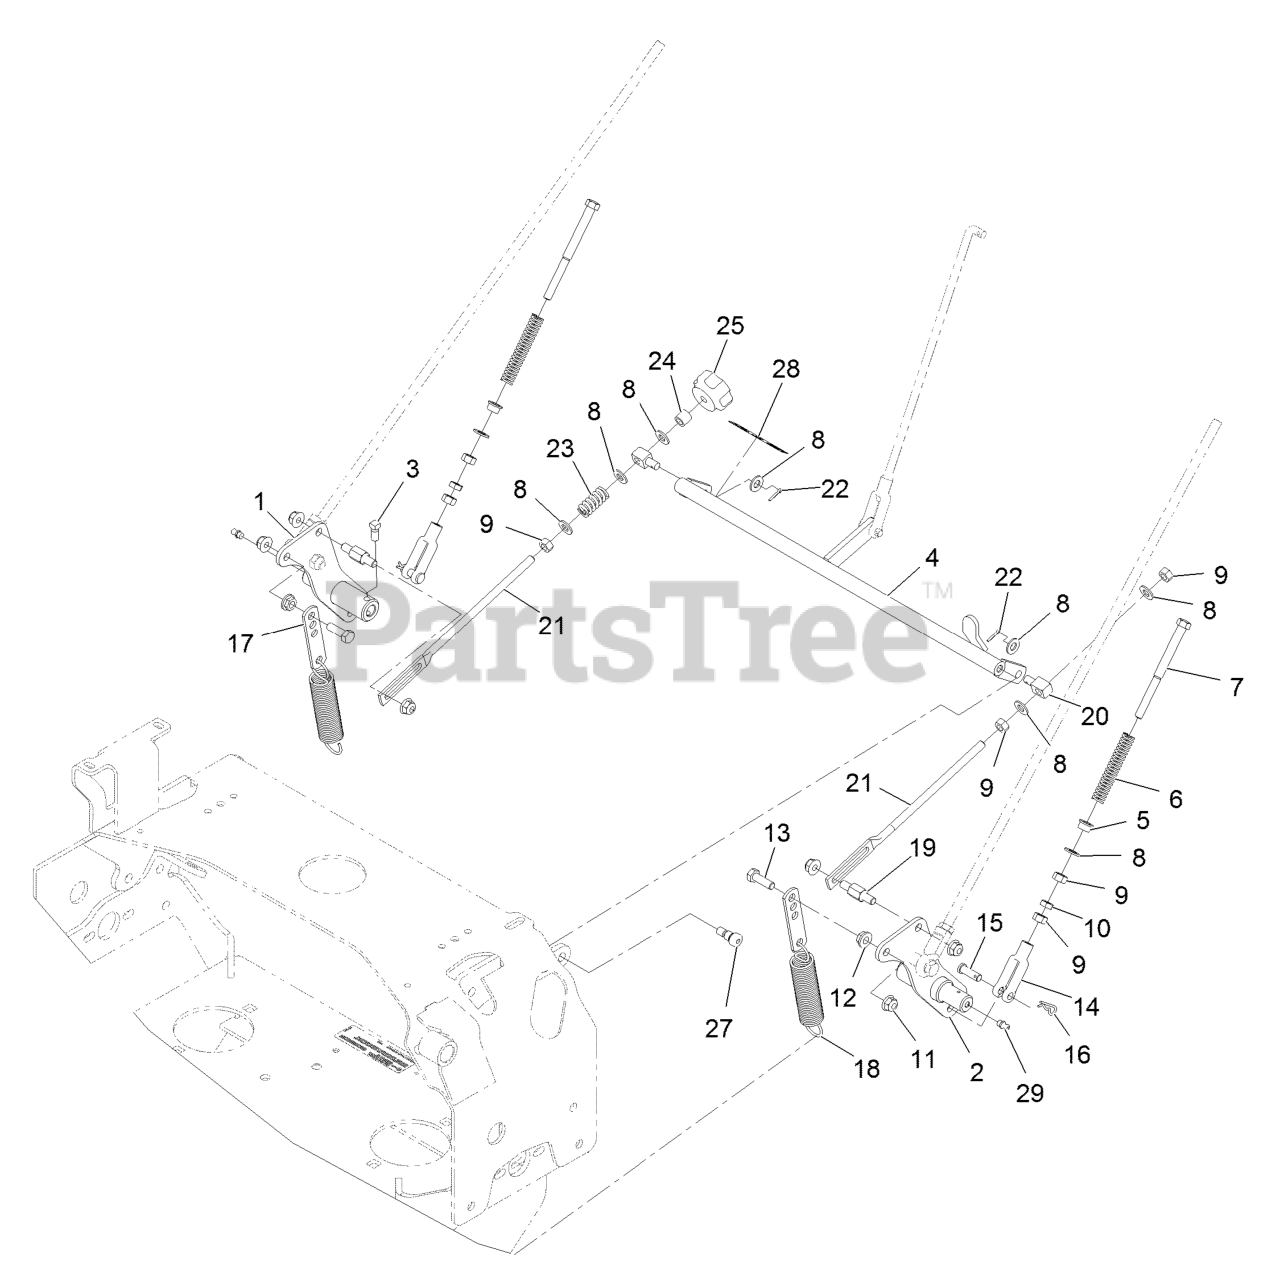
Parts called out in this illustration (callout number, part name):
1	WELD, MOTION CONTROL, RT
2	WELD, MOTION CONTROL, LT
3	SCREW-SET
4	WELD, SPEED CONTROL
5	BUSHING-FLANGED
6	SPRING,COMPRESSION (NEUT)
7	BOLT-RETURN, NEUTRAL
8	WASHER-PLAIN
9	NUT-HEX
10	NUT-JAM
11	NUT-HF, NI
13	SCREW-HH
14	YOKE-ADJUSTABLE
15	PIN-CLEVIS
16	PIN-COTTER
17	TAB-SPRING, EXTENSION
18	SPRING-EXTENSION
19	PIN, MOTION CONTROL
21	LINK-CONTROL, SPEED
22	PIN-COTTER
23	SPRING-COMPRESSION
25	KNOB-TRACKING
27	SCREW-HSH
28	DECAL-TRACKING ADJUSTMENT
29	FITTING-GREASE
